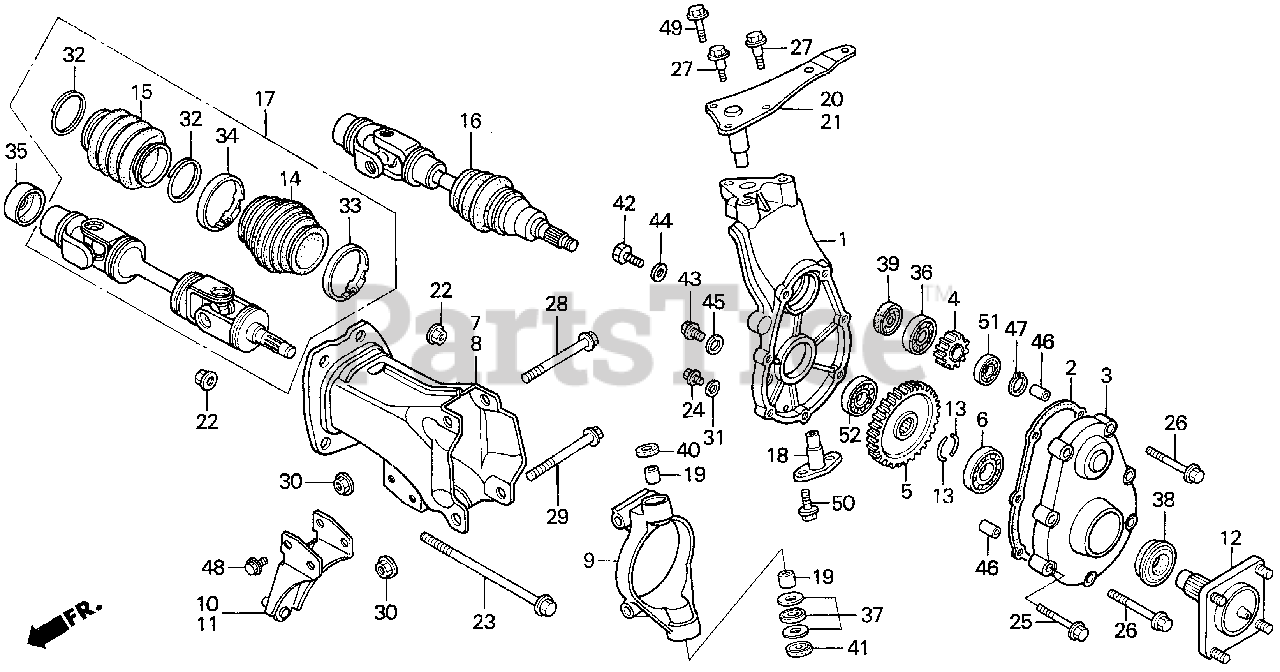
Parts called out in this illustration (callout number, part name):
1	CASE, FINAL REDUCTION
2	GASKET, FINAL REDUCTION
3	COVER, FINAL REDUCTION
4	GEAR, FR. FINAL DRIVE
5	GEAR, FR. FINAL DRIVEN
6	BEARING, RADIAL BALL SPECIAL (6206)
7	TUBE, R. FR. AXLE
8	TUBE, L. FR. AXLE
9	HOLDER, FINAL REDUCTION CASE
10	BRACKET, R. HANGER
11	BRACKET, L. HANGER
12	SHAFT, AXLE
13	KEY, AXLE SHAFT LOCK
14	BOOT, FR. JOINT (OUTER)
15	BOOT, FR. INSIDE JOINT
17	JOINT ASSY., FR. DRIVE
18	KINGPIN (LOWER)
19	BUSH, KINGPIN
20	ARM, R. FR. KNUCKLE
21	ARM, L. FR. KNUCKLE
22	NUT, SELF-LOCK (10MM)
23	BOLT, HEX. (10X144)
24	BOLT, SEALING (8MM)
25	BOLT, UBS (8X36)
26	BOLT, KNOCK (8X46)
27	BOLT, KNOCK (10X32)
28	BOLT, FLANGE (12X105)
29	BOLT, FLANGE (12X125)
30	NUT, SELF-LOCK (12MM) (SATO RASHI)
31	GASKET (8MM)
32	CLIP (50.7)
35	SEAL, JOINT
36	BEARING, RADIAL BALL (62/22)
37	BEARING, THRUST (17X30X9)
38	SEAL, WATER (32X52X11) (NOK)
39	OIL SEAL (24X42X7) (ARAI)
40	OIL SEAL (22X35X8)
41	OIL SEAL (25X38X8)
43	BOLT, DRAIN PLUG (14MM)
45	WASHER, DRAIN PLUG (14MM)
46	PIN, DOWEL (10X16)
47	CIRCLIP (OUTER) (17MM)
48	BOLT, FLANGE (10X16)
49	BOLT, FLANGE (10X25)
50	BOLT, FLANGE (10X28)
51	BEARING, RADIAL BALL (6203)
52	BEARING, RADIAL BALL (6205)
